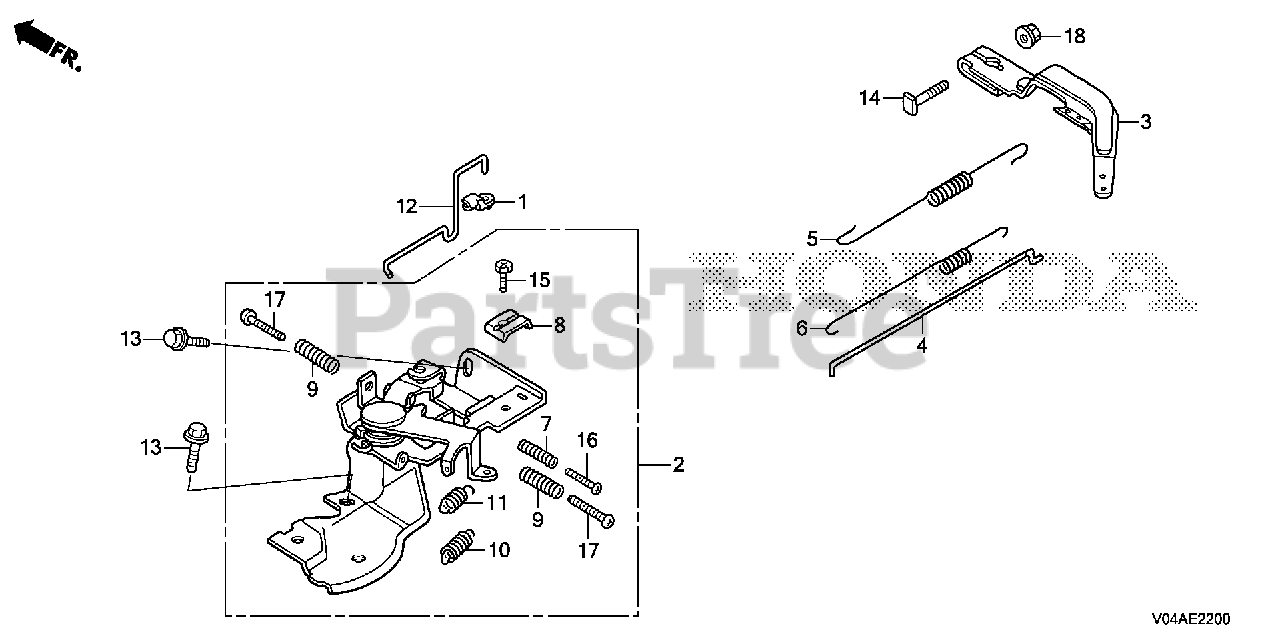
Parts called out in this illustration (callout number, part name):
1	JOINT, ROD
2	CONTROL ASSY.
3	ARM, GOVERNOR
4	ROD, GOVERNOR
5	SPRING, GOVERNOR
6	SPRING, THROTTLE RETURN
7	SPRING, CONTROL ADJUSTING
8	HOLDER, CABLE
9	SPRING, CONTROL ADJUSTING
10	SPRING, CABLE RETURN
11	SPRING, CABLE RETURN
12	ROD, CHOKE
13	BOLT, FLANGE (6X12) (CT200)
14	BOLT, GOVERNOR ARM
15	BOLT, RECESSED (5X16)
16	SCREW, PAN (4X20)
17	SCREW, PAN (5X20)
18	NUT, FLANGE (6MM)
